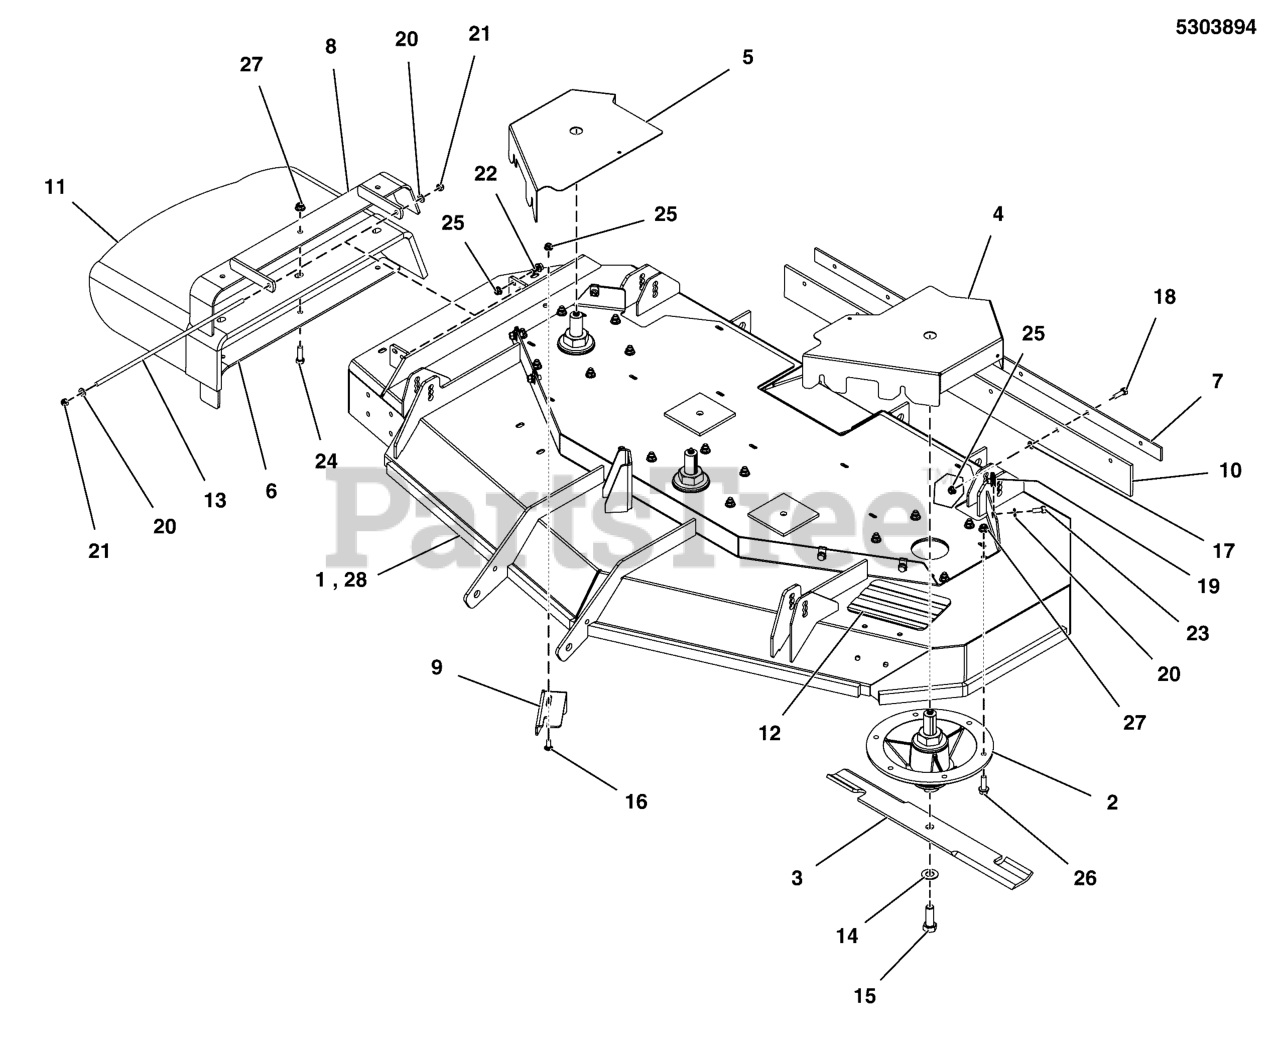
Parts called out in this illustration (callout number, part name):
1	DECK SHELL W/DECALS, 61, 3200-DOM (5413026B)
2	SPINDLE ASSEMBLY
3	BLADE SET, 61 DECK (3)
4	GUARD, IS3200Z, LH 61" - RED
5	GUARD, IS3200Z, RH 61" - RED
6	SUPPORT, DISCHARGE CHUTE - BLK
7	PLATE, SUPPORT - BLK
9	PLATE, DEFLECTOR - BLK
10	FLAP, STRIPER, 61 DECK, IS3100 S200X
11	CHUTE, RUBBER DISCHARGE (5104442)
12	SAFETY WALK, 9.75 X 6.00
13	ROD, MOUNT, CHUTE 61, CZ
14	WASHER, BLADE BOLT, 9/16" F436, CZ
15	BOLT, 5/8-11 X 1-3/4 GD8
16	BOLT, 5/16-18 X 3/4, CARRIAGE
17	5/16 PUSH-ON NUT RETAINER, STL, CZ
18	BOLT, 5/16-18 X 1 GD5 CZ
19	BODY CLIP, 5/16-18-7GA MATERIAL
20	WASHER, 5/16" SAE
21	NUT, 5/16-24 HEX NYLON LOCK
22	BOLT, 5/16-18 X 3/4 GD5
23	BOLT, 5/16-18 X 3/4 GD5
24	BOLT, 3/8-16 X 1-1/2, CARRIAGE, GD5, CZ
25	NUT, 5/16-18 HEX NYLOCK FLANGE
26	BOLT, 3/8-16 X 1-1/4, FLANGE, GD 5, CZ
27	NUT, 3/8-16 HEX NYLOCK FLANGE
28	DECK SHELL W/DECALS, 61, 3200-ANSI-EXP (5413026B)
